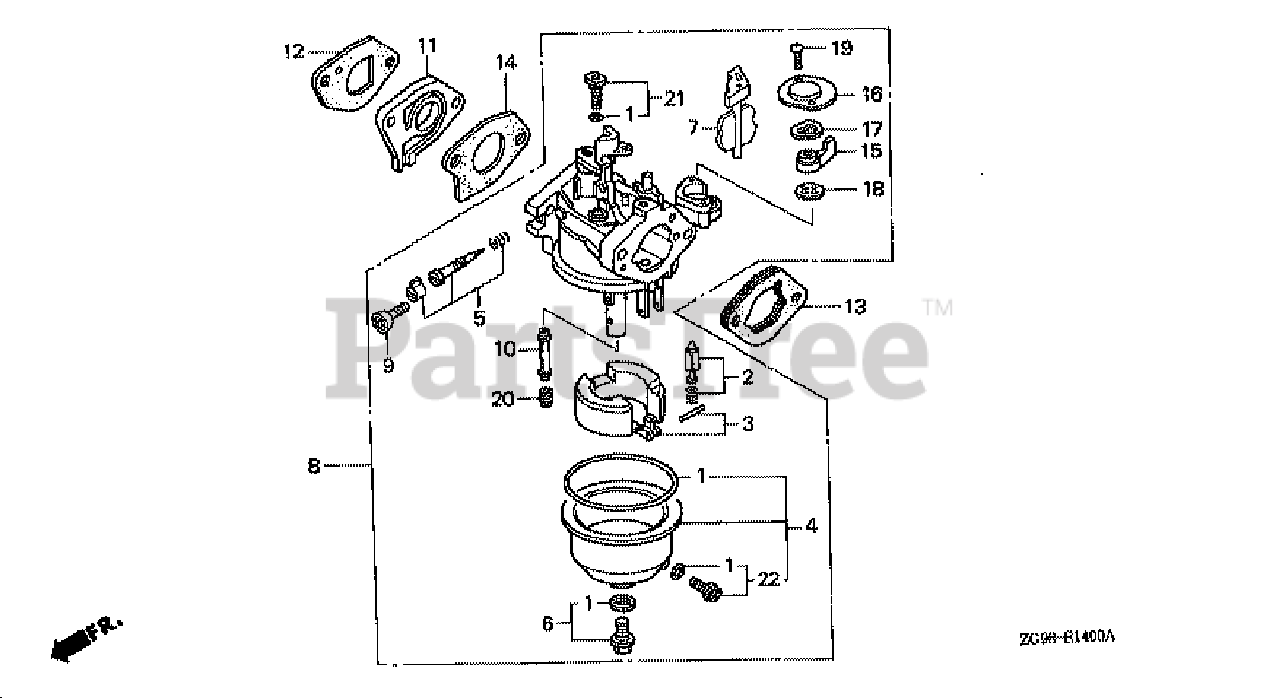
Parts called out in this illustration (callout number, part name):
1	GASKET SET
2	VALVE SET, FLOAT
3	FLOAT SET
4	CHAMBER SET, FLOAT
5	SCREW SET
6	SCREW SET B
7	CHOKE SET
8	CARBURETOR ASSY. (BE53A C)
9	SCREW, THROTTLE STOP
10	NOZZLE, MAIN
11	INSULATOR, CARBURETOR
12	GASKET, CARBURETOR (HPE)
13	SPACER, CARBURETOR
14	GASKET, CARBURETOR
15	LEVER, VALVE
16	PLATE, LEVER SETTING
17	SPRING, VALVE LEVER
18	GASKET, VALVE
19	SCREW, PAN (3X6)
20	JET, MAIN (#52)
20	JET, MAIN (#55)
20	JET, MAIN (#58)
21	JET SET, PILOT (#38)
22	SCREW SET, DRAIN
